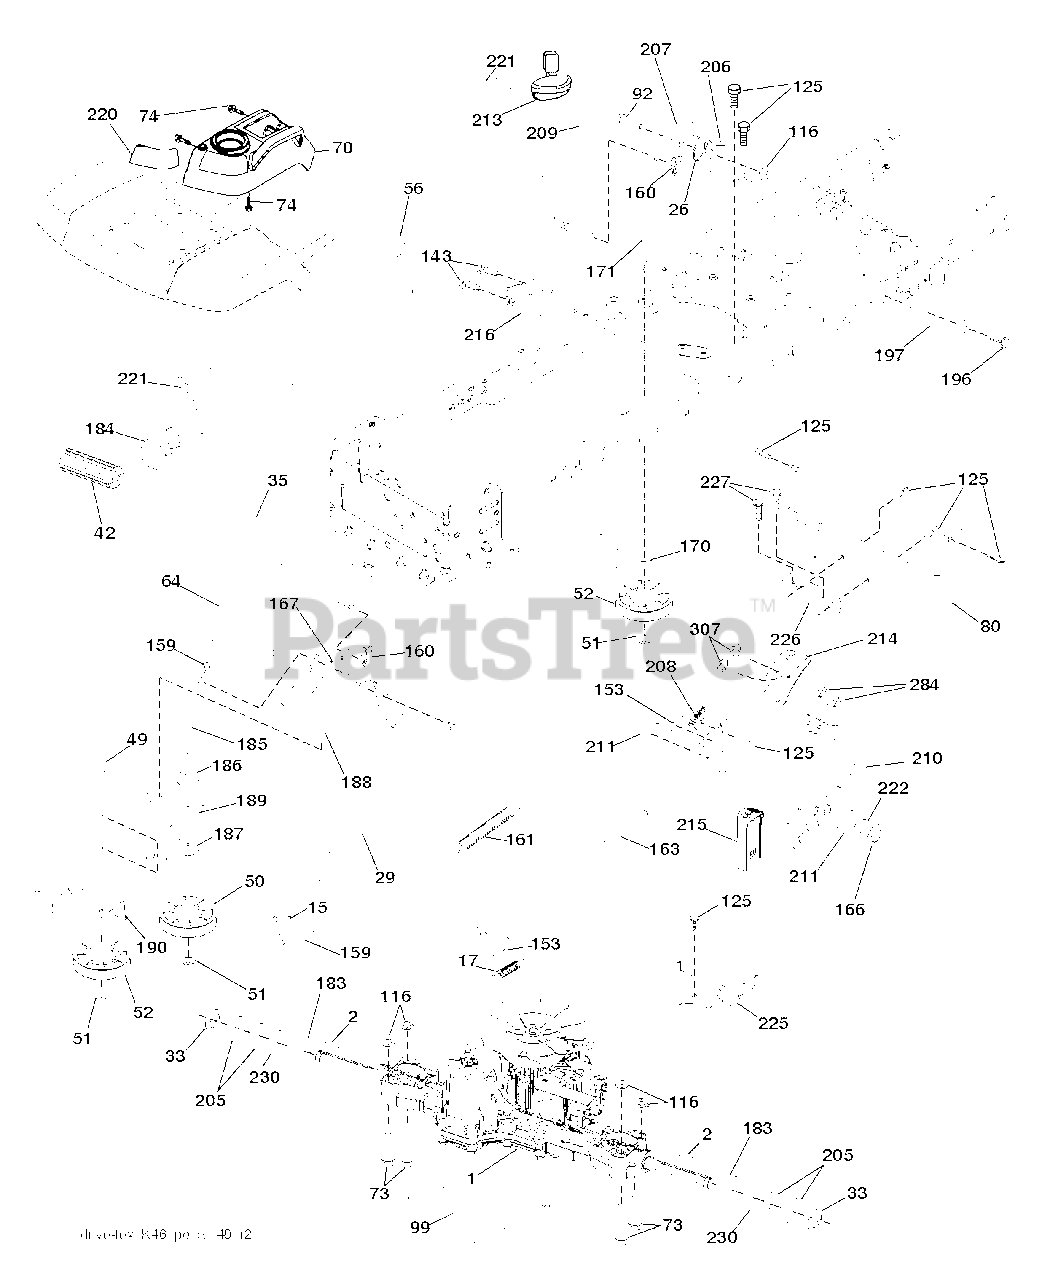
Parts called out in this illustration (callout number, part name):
2	SQUARE KEY
15	WASHER
17	SPRING.BRAKE.K46.GREEN
26	SPRING.RETURN.CRUISE
29	ROD.BRAKE.K46
33	E RING HYT
35	ROD .BRAKE. PARKING. GT. HUSQ.
42	PEDAL COVER T
50	IDLER.FLAT.910.OFFSET
51	NUT LOCK FLG 3/8-16 UNC
52	IDLER.V-GROOVE.910.OFFSET
56	V-BELT.MOWER.92.40.42/K46
64	SHAFT.ASM.PEDAL.BRK.CNTR
70	CONSOLE.ASM.RH.GT.FC.HUSQ
74	SCREW.HI-LO.CONSOLE
80	STRAP.TORQUE.K46.K57R.TT
92	BOLT
99	ROD.SPRING.BYPASS.K46.LT.Z
116	NUT LOCK HEX FLANGE 5/16-18
125	SCREW
143	SCREW LT
153	RETAINER M
159	COTTER PIN
160	RETAINER CLIP
161	SPRING, RETURN LT
163	ROD.CONTROL.K57R.K46
166	NUT.PUSH.625
167	LATCH.BRAKE.SPRING
170	KEEPER.V-IDLER.CENTER.
183	SPACER AXLE
184	RB HANDLE.PARKG.BRK.HUS/PRED
186	SPACER.RETAINER
187	WASHER 12/32X2X10GA
188	RP LINK.CLUTCH.GROUND.DRIVE
189	BELLCRANK.GROUND.DRIVE.TEX.
190	KEEPER.BELLCRANK.DRIVE
196	SCREW 3/8-16X1
197	LINK.CLUTCH.ANIT-ROTAT
206	BRACKET.MOUNT.CRUISE.LATCH
207	LATCH.CONTROL.CRUISE
208	GEAR.SECTOR.CONTROL.CR
209	ROD.CONTROL.CRUISE.GT.
210	ROCKER.ASM.PEDAL.CONTR
211	BEARING.NYLON
213	KNOB.CONTROL.CRUSIE.HU
214	PEDAL.FORWARD.HUSQVARNA.DEALER
215	PEDAL RUBBER REVERSE
216	BRACKET.PULLEY.IDLER.W/TEX
220	REFLECTOR.RH.TEX GT
221	RETAINER.SPRING.CLIP.H
222	WASHER 21/32 X 1-1/4 X 10 GA.
225	KEEPER.BELT.TRANSAXLE.K46
226	BRACKET.MOUNT.TORQUE.K46.TLT
227	SCREW
230	WASHER.HARDENED
284	NUT.U-CHNL.1/4-20.550DP.350PNL
307	SCREW.MACHINE.CR.1/4-20
